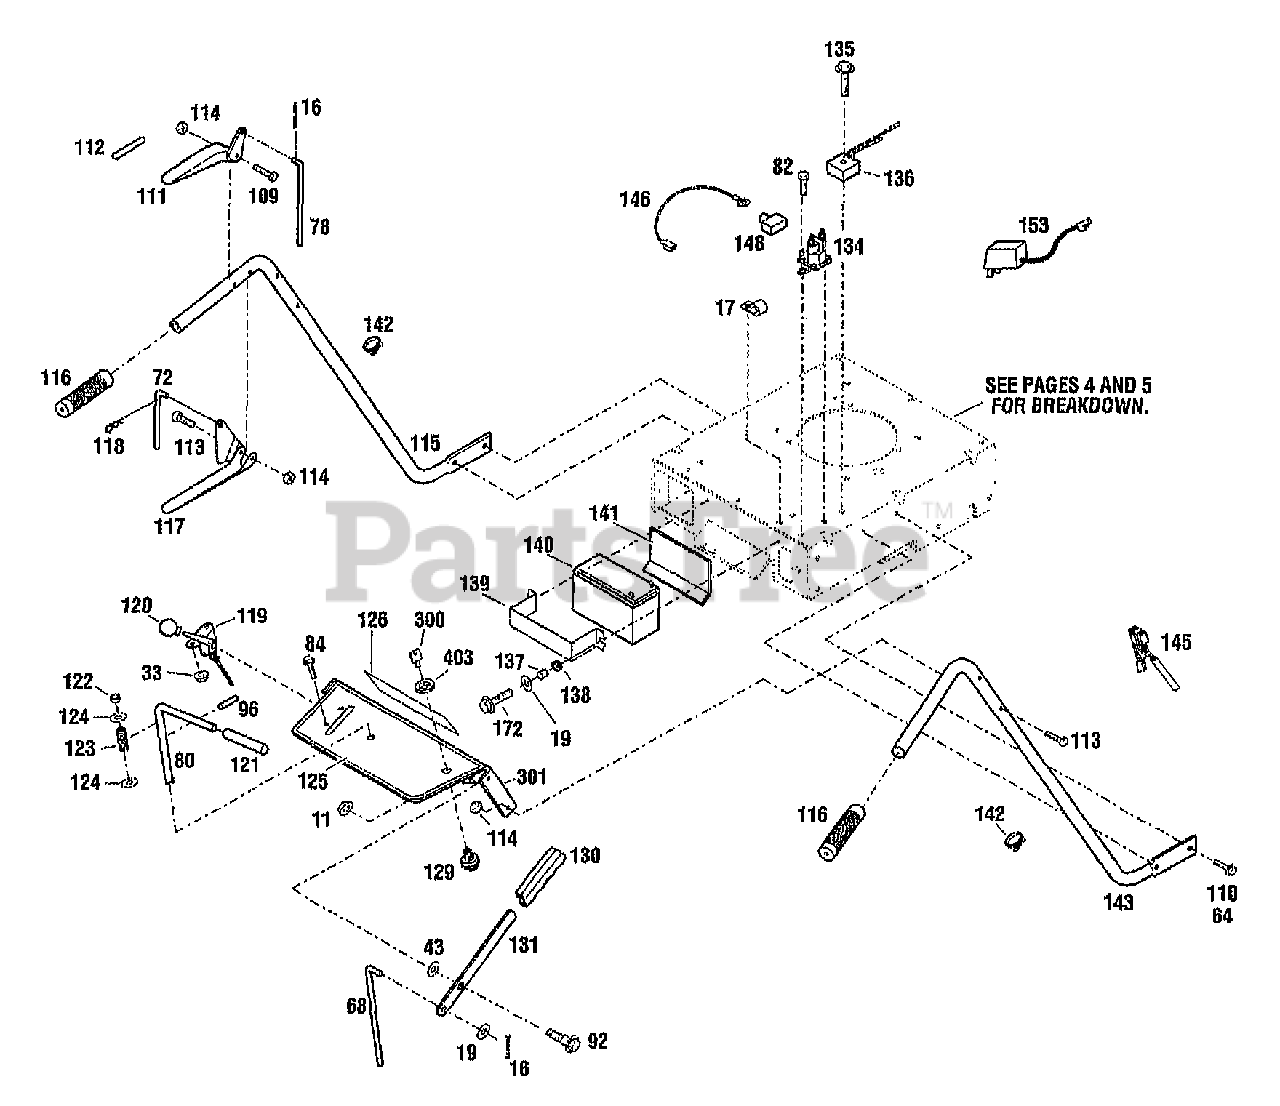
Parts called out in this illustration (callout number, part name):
11	NUT-HFLK 3/8-16 ZP
16	PIN-COTTER .093X.625
17	CLIP-CLAMP .25 ID
19	WASHER-FLAT 5/16 SAE
33	NUT-HF/LK 1/4-20 ZP
43	WASHER-FLAT 1.0X.516X.031
64	NUT-HFLK 5/16-18 ZP
68	ROD-UPPER BLADE
72	ROD-UPPER CONTROL
78	ROD-UPPER BRAKE
80	LEVER-SHIFT
82	SCR 1/4-20X.5 FL SELF TAP {34087,34087C}
84	SCR-HFLK 1/4-20X.50 ZP
92	BOLT-SHOULDER MOWER
96	PIN-ROLL .25X2.25
109	SCR-HH 1/4-20X1.75 G5 ZP {34089,34089C, 34087,34087C
109	SCR-HH 1/4-20 X 1.75 GR8 ZP {34342,34343}
110	SCR-HFLK 5/16-18X.75 ZP
111	LEVER-CONTROL
112	DECAL-OPC MOWERS
113	SCR-HH 1/4-20X1.5 G5ZP {34089,34089C,34087, 34087C}
113	SCR-HH 1/4-20 X 1.75 GR8 ZP {34342,34343}
114	NUT-HT LK 1/4-20
115	HANDLEBAR-LH
116	GRIP-FLEX
117	LEVER-CONTROL
118	PIN-CLIP .08
119	CABLE-THROTTLE CONTROL
120	KNOB
121	GRIP-HANDLE
122	BUSHING-.5X.21 NYLON FLNG
123	SPRING-COMPRESSION
124	WASHER-1.06X.531X.1 ZP
125	DECAL-WARNING STD WC {34089,34089C}
125	DECAL-WARNING ELEC WC {34087,34087C}
125	DECAL-WARNING STD WC {34342}
125	DECAL-WARNING ELEC WC {34343}
126	DECAL-WIDE CUT T/B
129	ASSM-KEYSWITCH {34087,34087C,34343}
130	GRIP-HANDLE
131	LEVER-MOWER ENGAGE ZP
134	SOLENOID {34087,34087C,34343}
135	SCR-HFLK {34087,34087C}
136	REGULATOR
137	SPACER {34087,34087C,34343}
138	GROMMET {34087,34087C,34343}
139	BRACKET-BATTERY {34087,34087C,34343}
140	BATTERY {34087,34087C}
140	BATTERY-ES1212 {34343}
141	PAD-BATTERY {34087,34087C,34343}
142	TIE-CABLE NYLON BLACK
143	HANDLEBAR-RH
145	HARNESS-WIRING {34087,34087C}
145	HARNESS-WIRE {34343}
146	ASSM-WIRE LEAD {34087,34087C}
146	ASSM-WIRE LEAD {34343}
148	BOOT-CABLE {34087,34087C,34343}
153	CHARGER-BATTERY {34087,34087C} (SHIPPED LOOSE)
172	SCR-HFLK 5/16-18X.75
300	KEY-IGNITION {34087,34087C,34343}
301	ASSM-CONSOLE {34089,34089C} (INCL. 125)
301	ASSM-CONSOLE {34087,34087C} (INCL. 125)
403	NUT-IGNITION SWITCH
